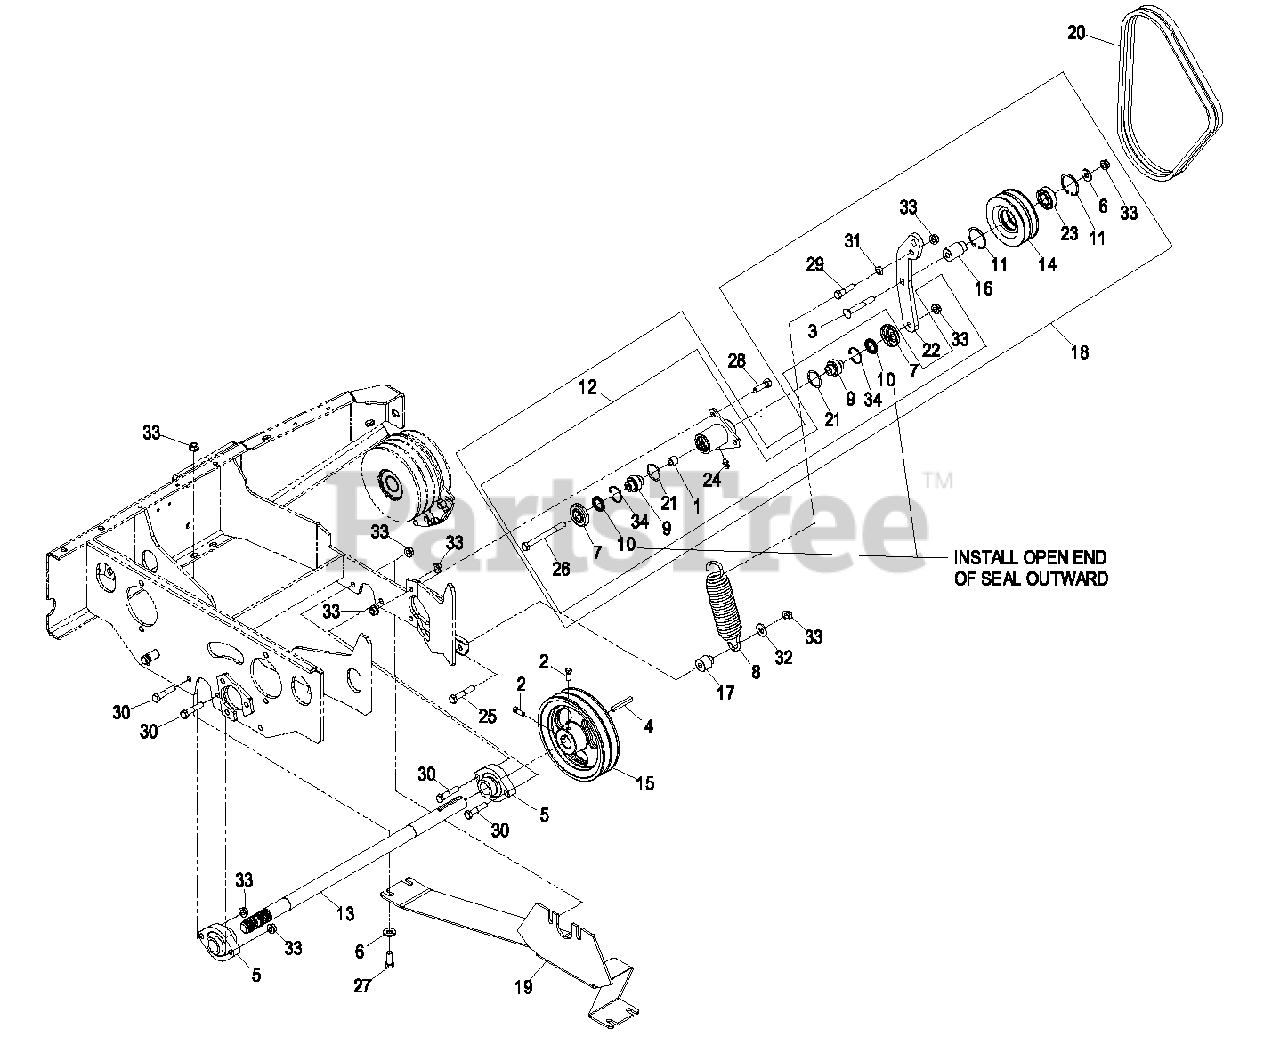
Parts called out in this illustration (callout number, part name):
1	BUSHING-LEVER, LIFT
2	SCREW-SET
3	BOLT,CARRSSN
4	KEY-SQUARE
5	BEARING-FLANGE
6	WASHER-BELLEVILLE
7	GUARD-TOP
9	BEARING-SPHERICAL
10	SEAL-LIP, SINGLE
11	RING-RETAINING
12	KIT,'04 XP PUMP IDLER
13	SHAFT, LINE
15	SHEAVE, 2-A
16	SPACER, IDLER BEARING
17	SPACER, SPRING .75
18	ASM, LINEDRIVE IDLER
19	GUARD, LINEDRIVE
23	BEARING-BALL
24	FITTING-GREASE, 90 DEG
25	SCREW-HH
26	SCREW-HH
27	SCREW-HH
28	SCREW-HH
29	SCREW-HH
30	SCREW-HH
31	NUT-JAM
32	WASHER-FLAT
33	NUT-HHF, WHIZ
34	RING-SNAP
